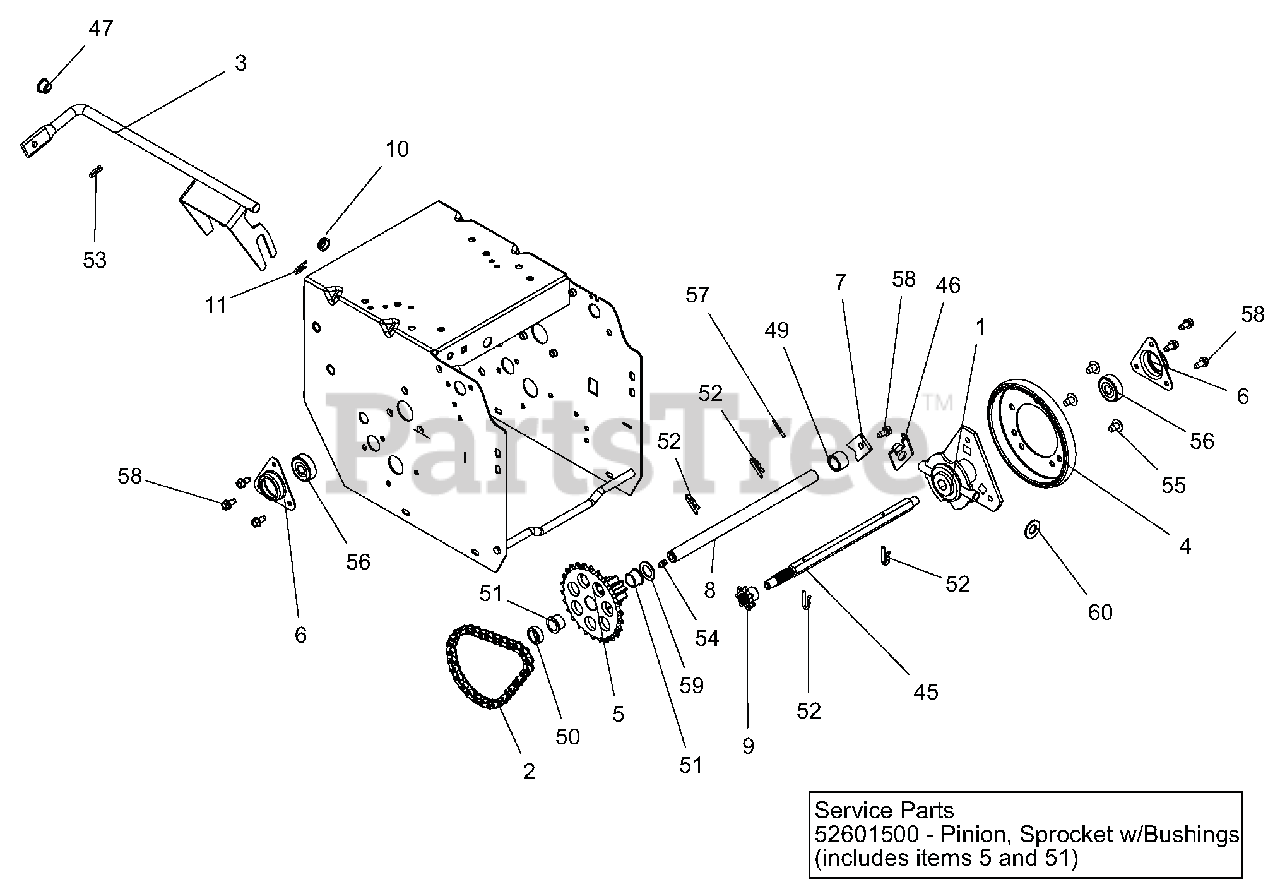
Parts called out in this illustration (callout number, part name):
1	CARRIER, DRIVE DISK
2	CHAIN - #41, 32 PITCHES
3	WELDMENT, SHIFT FORK
4	FRICTION, DISC
5	PINION & SPROCKET
6	FLANGE, BEARING
7	TAB, ANTI ROTATION
8	SHAFT, PINION
9	SPROCKET, PINION 7T W/SPLINE
10	BUSHING, POLYLINER-.50 SNAPIN
11	CLIP, SPRING
45	SHAFT, HEX W/SPLINE
46	BRACKET, FORMED - SHIFT FORK
47	BUSHING, POLYLINER-.50 SPLIT
49	SPACER, .635X.880X.611
50	BSHG-SLV, .635X.880X.305
51	BSHG-FLG .625X.750X.500X.875
52	PIN, SPRING CLIP
53	CLIP, SPRING
54	ZERK,FITTING .25X.125 DRIVE IN
55	SCR-TAP SERRDHDTX .31-18X.50BP
56	BRG-BALL .437X1.375X.437
57	@PIN-GRV .125X1.00 TP E ALLOY
58	SCR-TAP .25-20X.50 HWH TR YWZ
59	WSHR-FL-STL .630X1.005X.062 YZ
60	WSHR-FL-STL .505X1.00X.062YWZC
